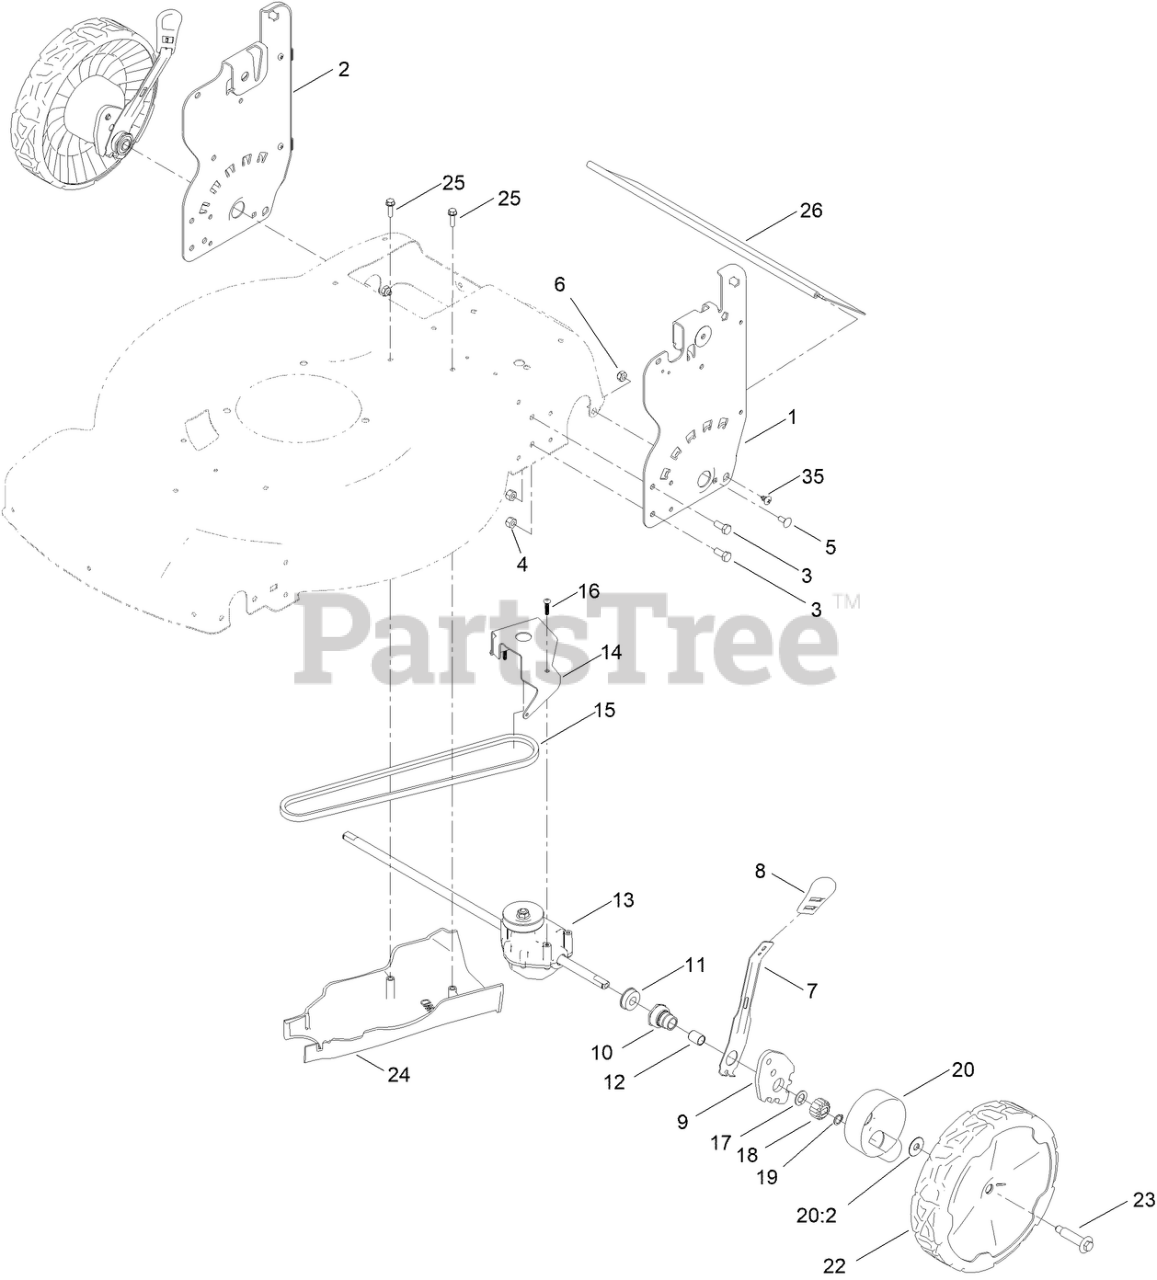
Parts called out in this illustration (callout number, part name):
1	PLATE-HOC, LH
2	PLATE-HOC, RH (ISO)
3	SCREW-HH
4	NUT-LOCK, NI
5	SCREW-CARR
6	NUT-LOCK, NI
7	ARM-SPRING
8	KNOB-HOC
9	ARM-PIVOT, REAR
10	RETAINER-BUSHING, HOC
11	BEARING-BALL
12	BUSHING-SLEEVE
13	TRANSMISSION-RWD
14	BRACKET-TRANSMISSION
15	V-BELT
16	SCREW-PLASTITE
17	WASHER-THRUST
18	GEAR-PINION, 15T
19	RING-RETAINING
20	ASM-COVER, GEAR (DK GRAY)
20:2	WASHER-STEPPED
22	ASM-9.65" WHEEL, GEARED
23	WHEEL BOLT
24	COVER-BELT, RWD
25	SCREW-HWH
26	SHIELD-TRAILING
35	SCREW-PTH
